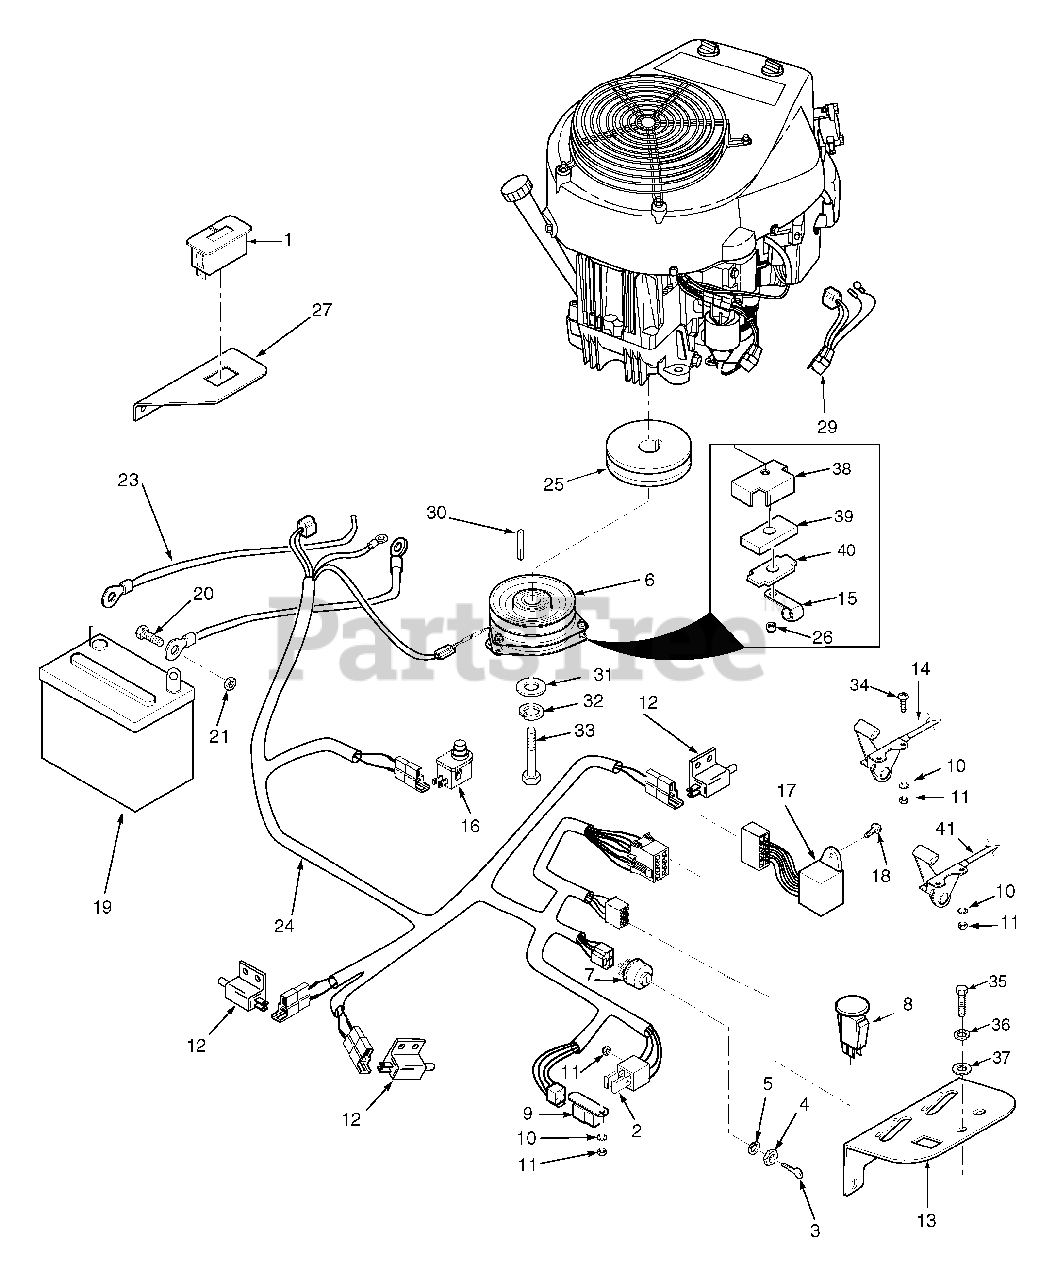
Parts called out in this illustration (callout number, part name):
1	Hourmeter
2	Fuse, 20 amp
3	Key, Ignition
4	Nut, Hex 5/8-32
5	Lockwasher, 5/8" Internal
6	Electric PTO Clutch GT3.5
7	Switch, Ignition
8	Switch, PTO
9	Relay
10	Lock Washer, #10 External Tooth
11	Nut, Hex #10-32
12	Switch, N/O
13	Panel, Instrument
14	Choke Control - Kohler (Qty 1)
16	Switch, Seat
17	Module, Interlock
18	Screw, #10-32 x .5" Phillips Head
19	Battery (Not Available Through Scag)
20	Bolt, Hex Head 1/4-20 x .5"
21	Nut, Hex 1/4-20
22	Cable, Battery Black (negative)
23	Cable, Battery Red (positive)
24	Wiring Harness, Main
25	Pulley, 5.45 OD x 1.125 Bore
26	Nut, Elastic Stop 5/16-18 Key
27	Mounting Bracket, Hour Meter
28	Screw, #10-32 x 1.5" Phillips Head
29	Adaptor, Wiring Harness
30	Key, 1/4 x 1/4 x 3-1/4"
31	Flatwasher, 7/16-.469 x 1-3/4" x 1/4"
32	Lockwasher, 7/16"
33	Bolt, Hex Head 7/16-20 x 2-1/4" UNF (61A Only)
34	Screw, #10-32 x 3/4"
35	Bolt, Hex Head 5/16-18 x 3/4"
36	Lockwasher, 5/16
37	Flatwasher, 5/16-.375 x .875 x .083
38	Backing Plate
39	Rubber Pad, Clutch Stop
40	Plate, Backing
41	Throttle Control - Kohler & Kawasaki (Qty 1)
